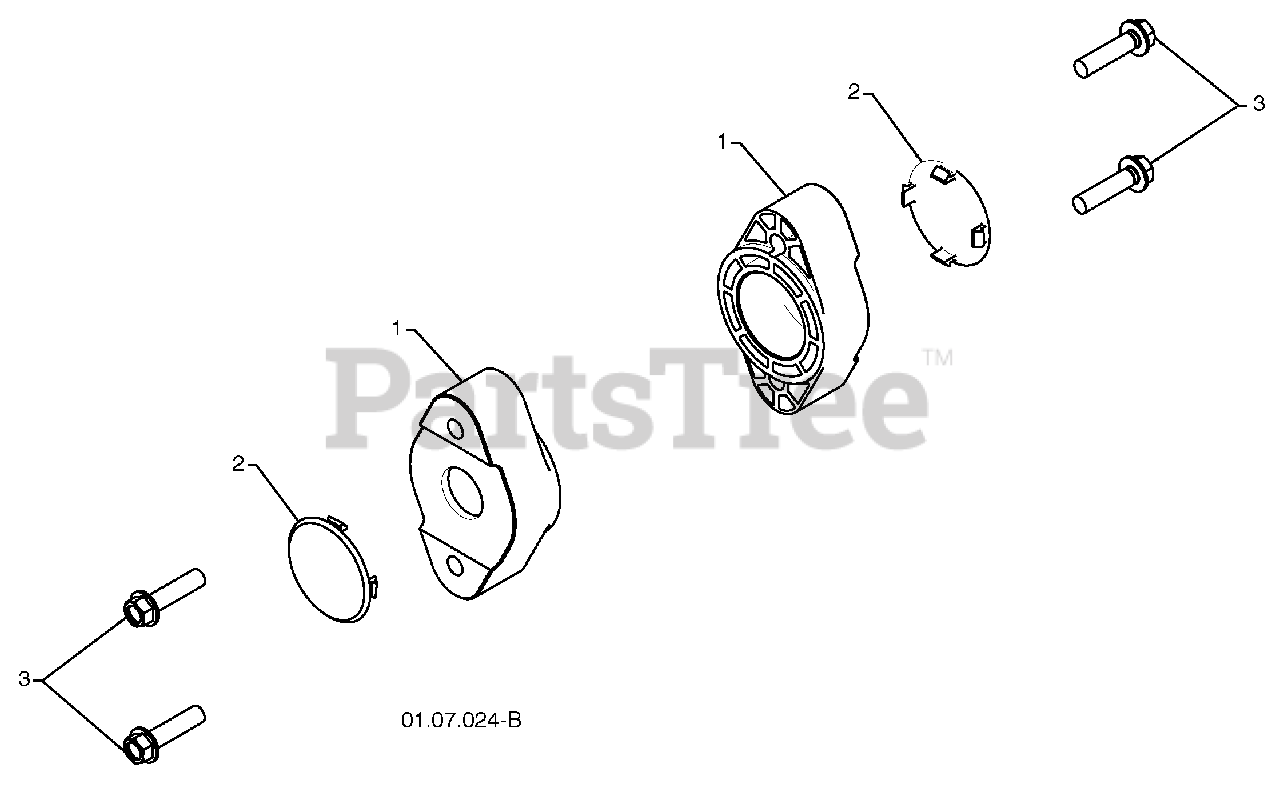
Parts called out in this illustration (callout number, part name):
1	AUGER BEARING
2	BEARING PLUG
3	SCREW 5/16-18 X 1.00
